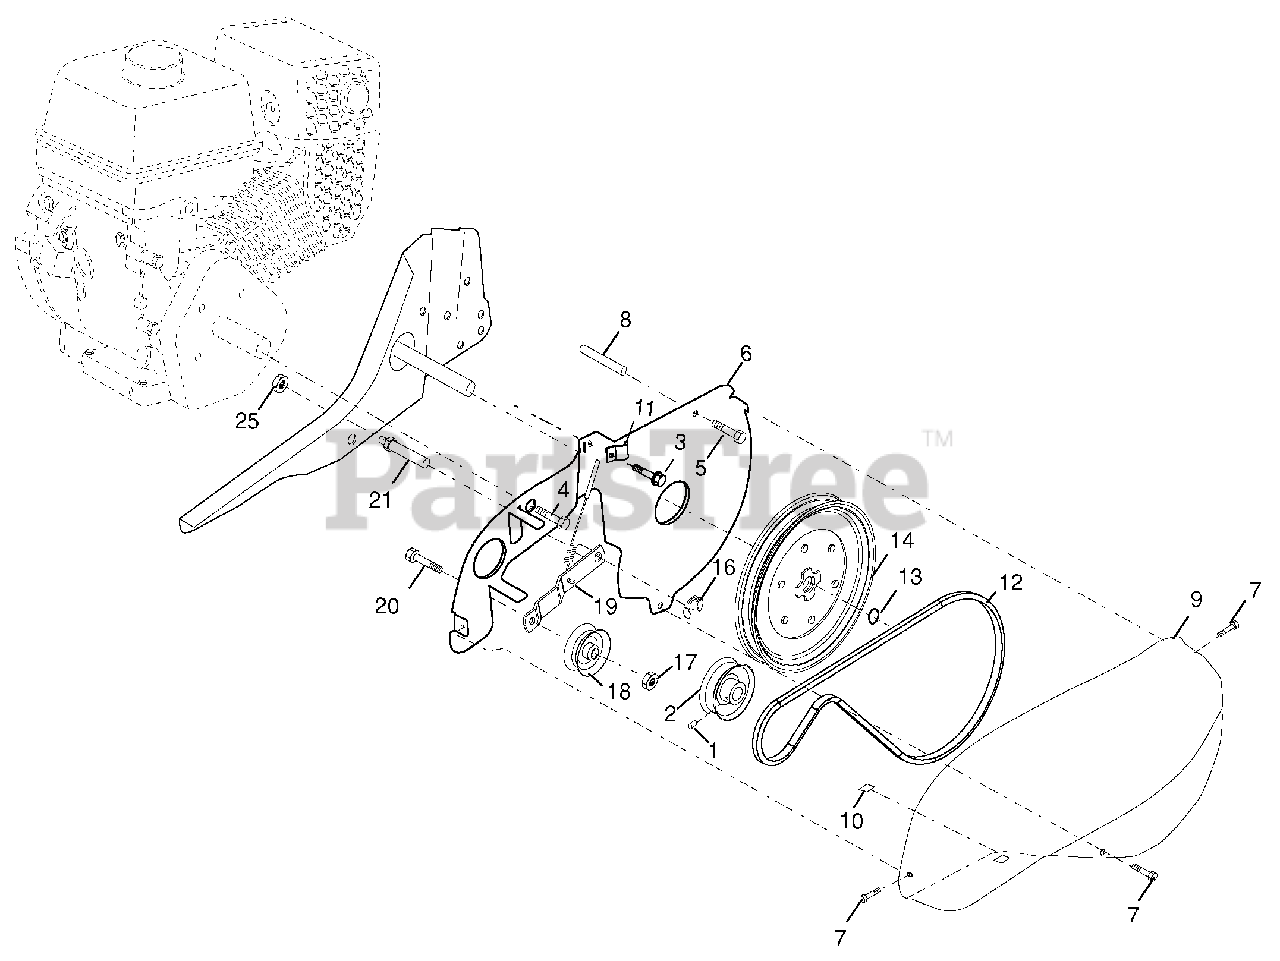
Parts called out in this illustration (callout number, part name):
1	Screw Set 5/16-18 x 3/8 Patch
2	Sheave, Engine
3	Screw, Tap Hex Head
4	Bolt, Hex 5/16-24 unf x 1/2
5	Bolt, Thd Roller 1/4-20 x 2-1/2
6	Shield, Inner Belt Guard
7	Screw Hex Wsh Hd #8-18 x 1/2
8	Spacer Split
9	Guard, Belt
10	Pad, Idler
11	Clip, Cable
12	V-Belt
13	Ring, Retainer
14	Sheave, Transmisison
16	Ring, Klip
17	Nut, Hex, Jam 3/8-16
18	Pulley, Idler
20	Bolt, Hex Head 3/8-16 x 1-1/4
21	Shaft, Idler Arm
25	Nut, Hex, Jam 5/16-18
